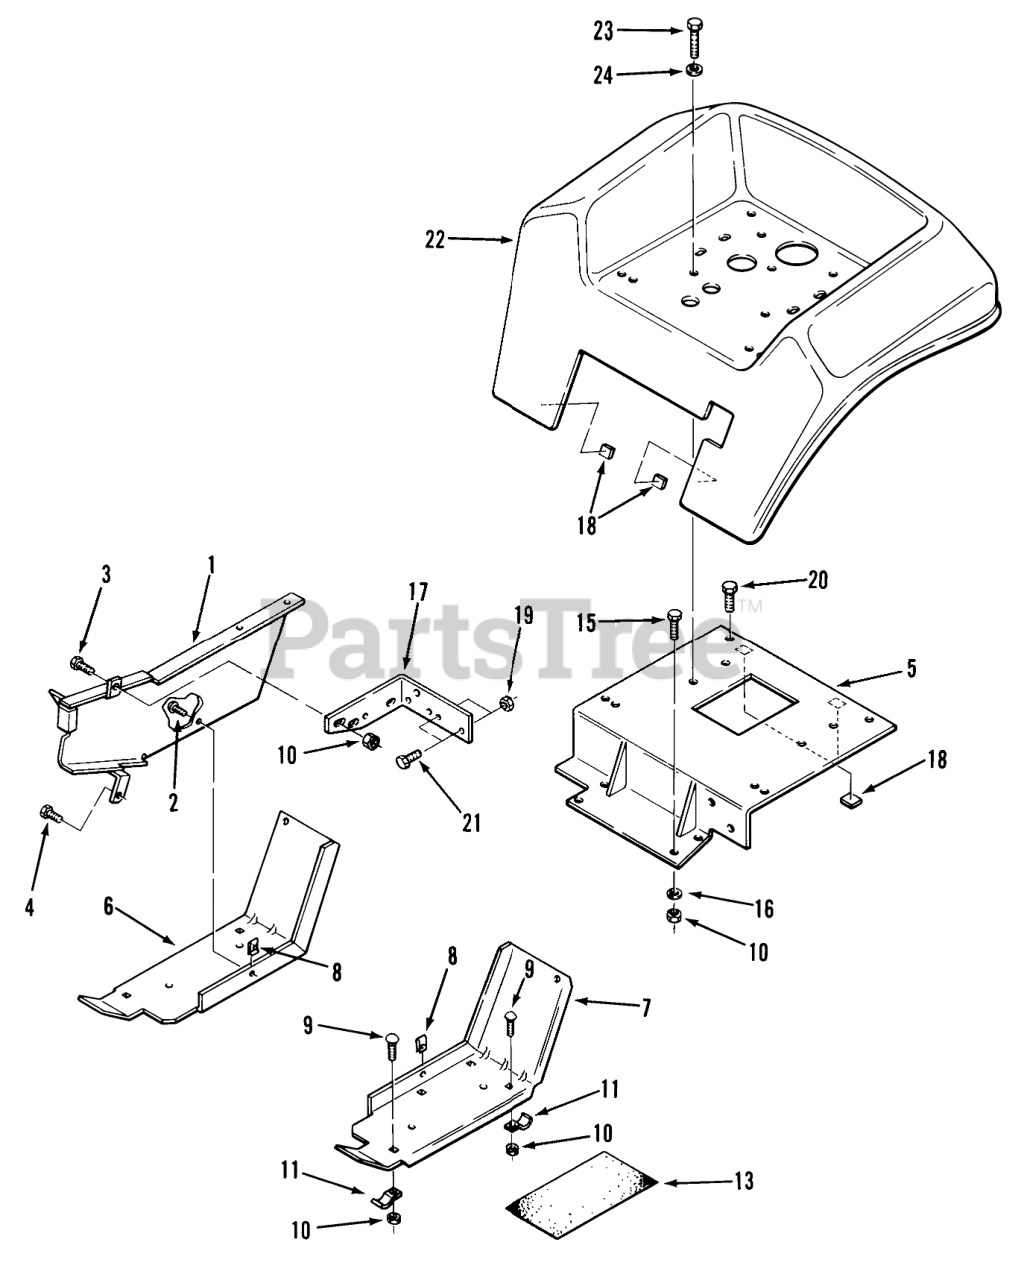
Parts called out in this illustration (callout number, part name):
1	Belt Guard
2	Screw
3	Bolt
4	SCREW
5	Fender Support (Illustrated) 01-19KE01 Only
5	Fender Support 01-19KE02 Only
6	Footrest-RH
7	FOOTREST LH R
9	CARRIAGE BOLT -4
10	Nut
11	BRACKET
13	PAD-FOOTREST
15	Bolt
16	WASHER 5/16 SAE
17	BRACKET-BELTB
18	BUMPER
19	Nut
20	Bolt
21	H H C S
22	Fender (Illustrated) 01-19KE01 Only
22	Fender 01-19KE02 Only
23	S.T. Bolt 5/16-18 x 1 1/2
24	WASHER 5/16 SAE
